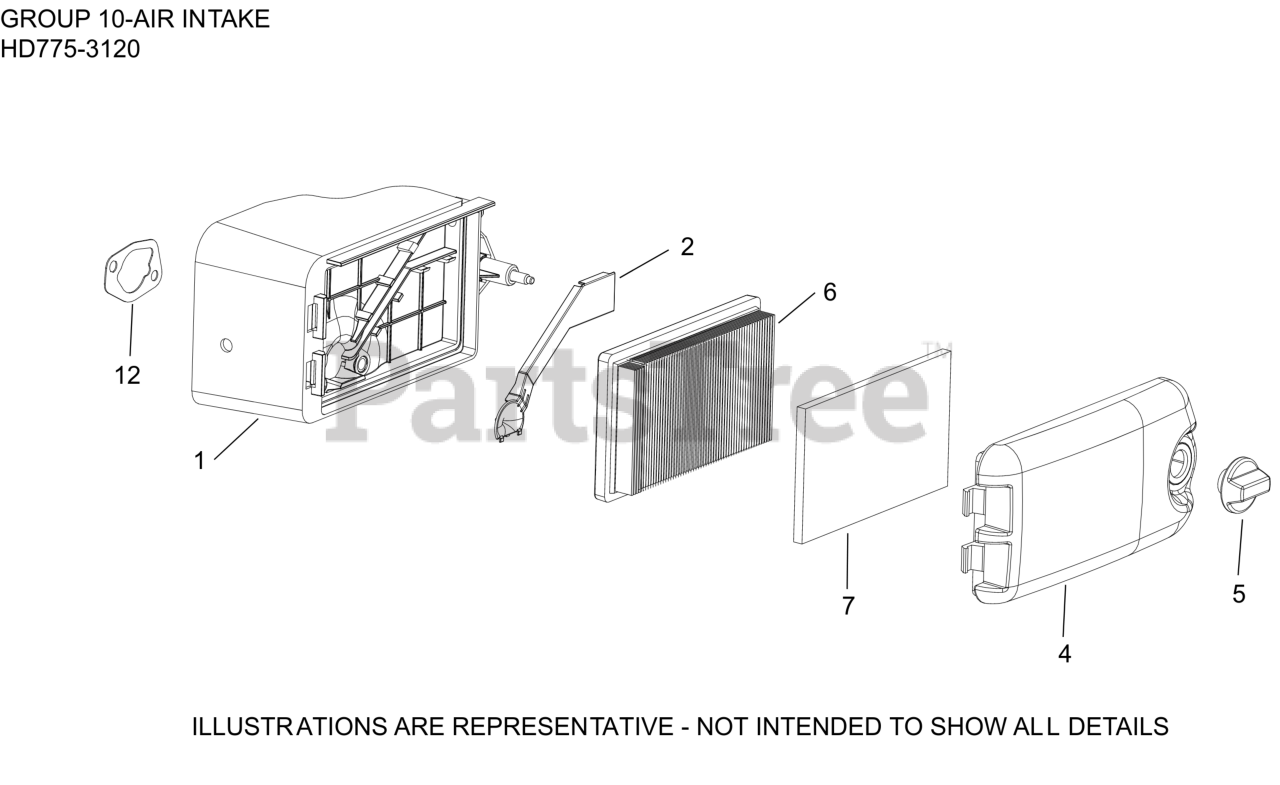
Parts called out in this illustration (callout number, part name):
1	AIR CLEANER BASE-USE 14 094 23-S
2	COVER, A/C BASE (BREATHER GAS)
4	COVER, AIR CLEANER
5	KNOB, AIR CLEANER
6	ELEMENT, AIR FILTER
7	ELEMENT, PRE-CLEANER
12	GASKET, AIR CLEANER BASE
